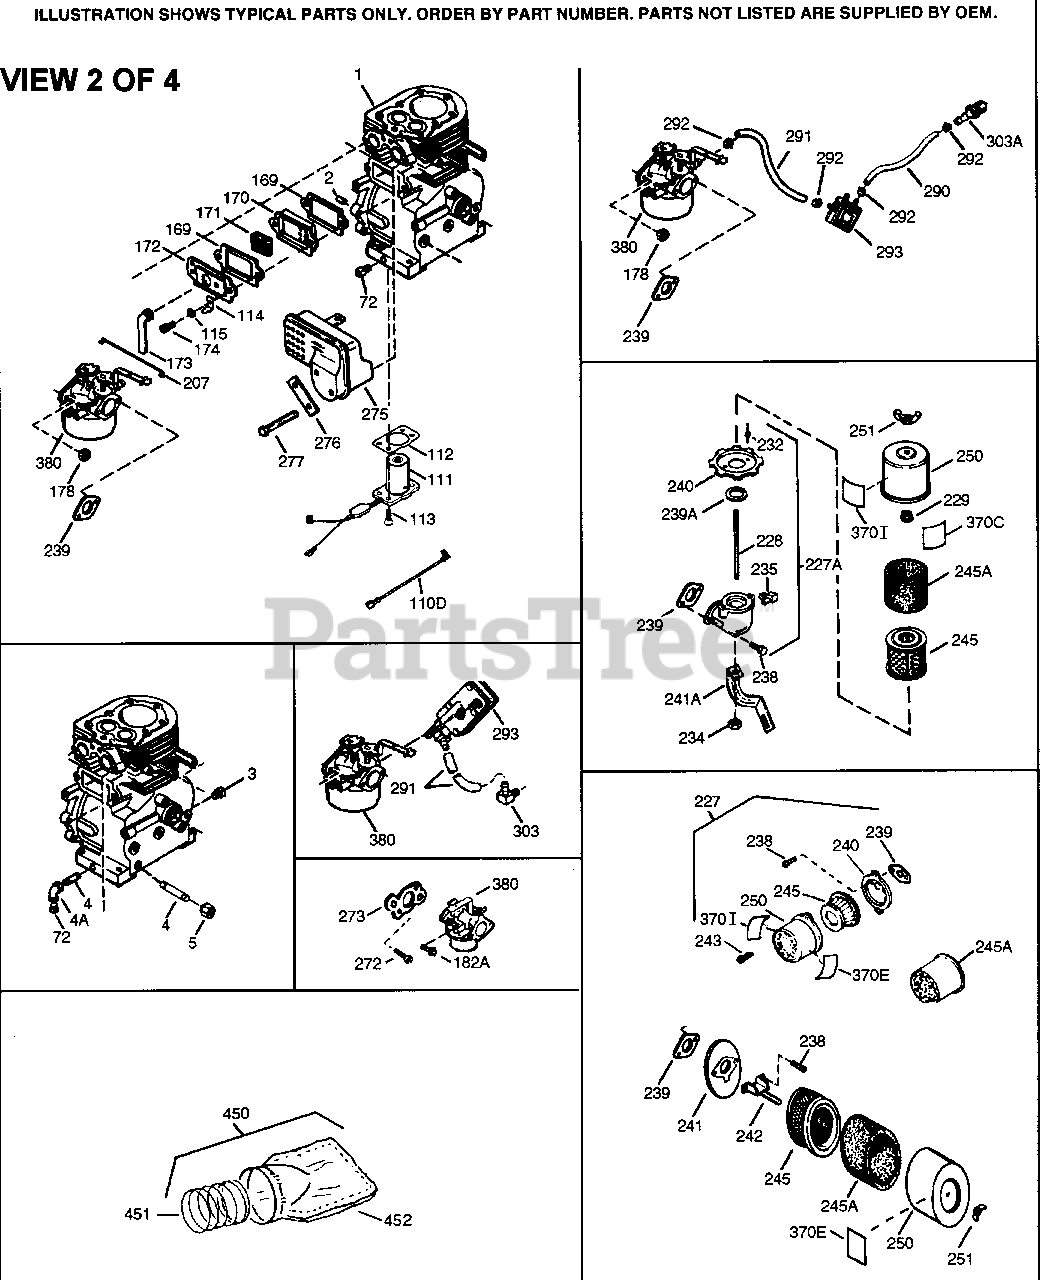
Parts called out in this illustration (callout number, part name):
1	"Cylinder Ass'y. (Incl. 2, 20, 72 & 72 A)(3-1/8" Bore)
2	Dowel Pin
4	Oil Drain Extension Purchase Locally
5	Extension Cap
14	Flat Washer
72	Oil Drain Plug (Sq. hd., 1/4-18)
169	* Breather Gasket
170	Breather Body
171	Breather Element
172	Valve Cover
173	Breather Tube
174	Screw, 10-24 x 1/2"
178	Nut & Lock Washer 1/4-28
207	Choke Link
212	Bushing
239	* Air Cleaner Gasket
240	Air Cleaner Bracket
242	Air Cleaner Bracket
243	Screw, 10-32 x 1/2"
245	Air Filter (Paper) also available in Packaged Part #740027B
245A	Poly Pre-Filter (also available in Pa ckaged Part #740027B)
250	Air Cleaner Cover
251	Wing Nut, 1/4-20
275	Muffler
276	Locking Plate
277	Screw, 5/16-18 x 3/3-16"
277A	Screw, 5/16-18 x 3-31/32"
280	Heat Shield
291	Fuel Line
292	Fuel Line Clamp
380	Carburetor (Incl. 184)
900	Replacement engine None.
900	Replacement short block 756331B, orde r from 71-999.
